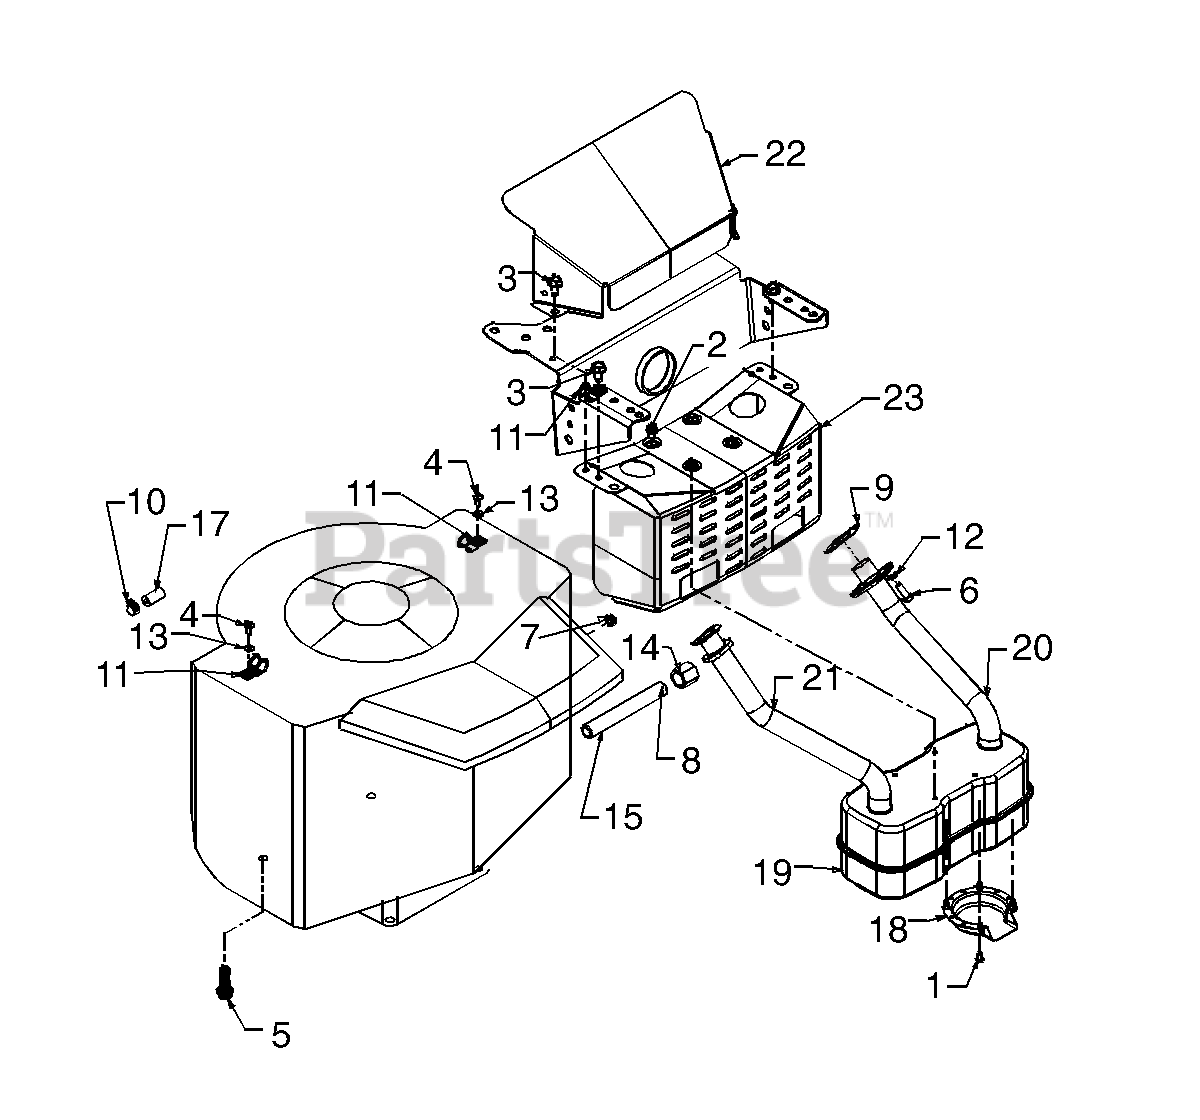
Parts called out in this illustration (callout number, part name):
1	Hex Tap Scr. #8-32 x .38" Lg.
2	Hex Wash. TT-Tap Scr. 1/4-20 x 5"
3	Hex Wash. TT-Tap Scr. 5/16-18 x .62"
4	Truss Mach. Scr. #10 x .5"
5	Hex Hd. Tap Scr. 3/8-16 x 1.25"
6	Hex Bolt 1/4-20 x .75" Lg.
7	Hex Sems Nut 1/4-20 Thd.
9	Exhaust Gasket
10	Hose Clamp
11	Clamp
12	L-Wash. 1/4" I.D.
13	Fl-Wash. .188" I.D. x .438" O.D.
14	Oil Drain Cap
15	Pipe Nipple 3/8 x 18 NPT.
17	Fuel Line 26" Lg.
18	Deflector: Muffler
19	Muffler
20	Exhaust Pipe-L.H.
21	Exhaust Pipe-R.H.
